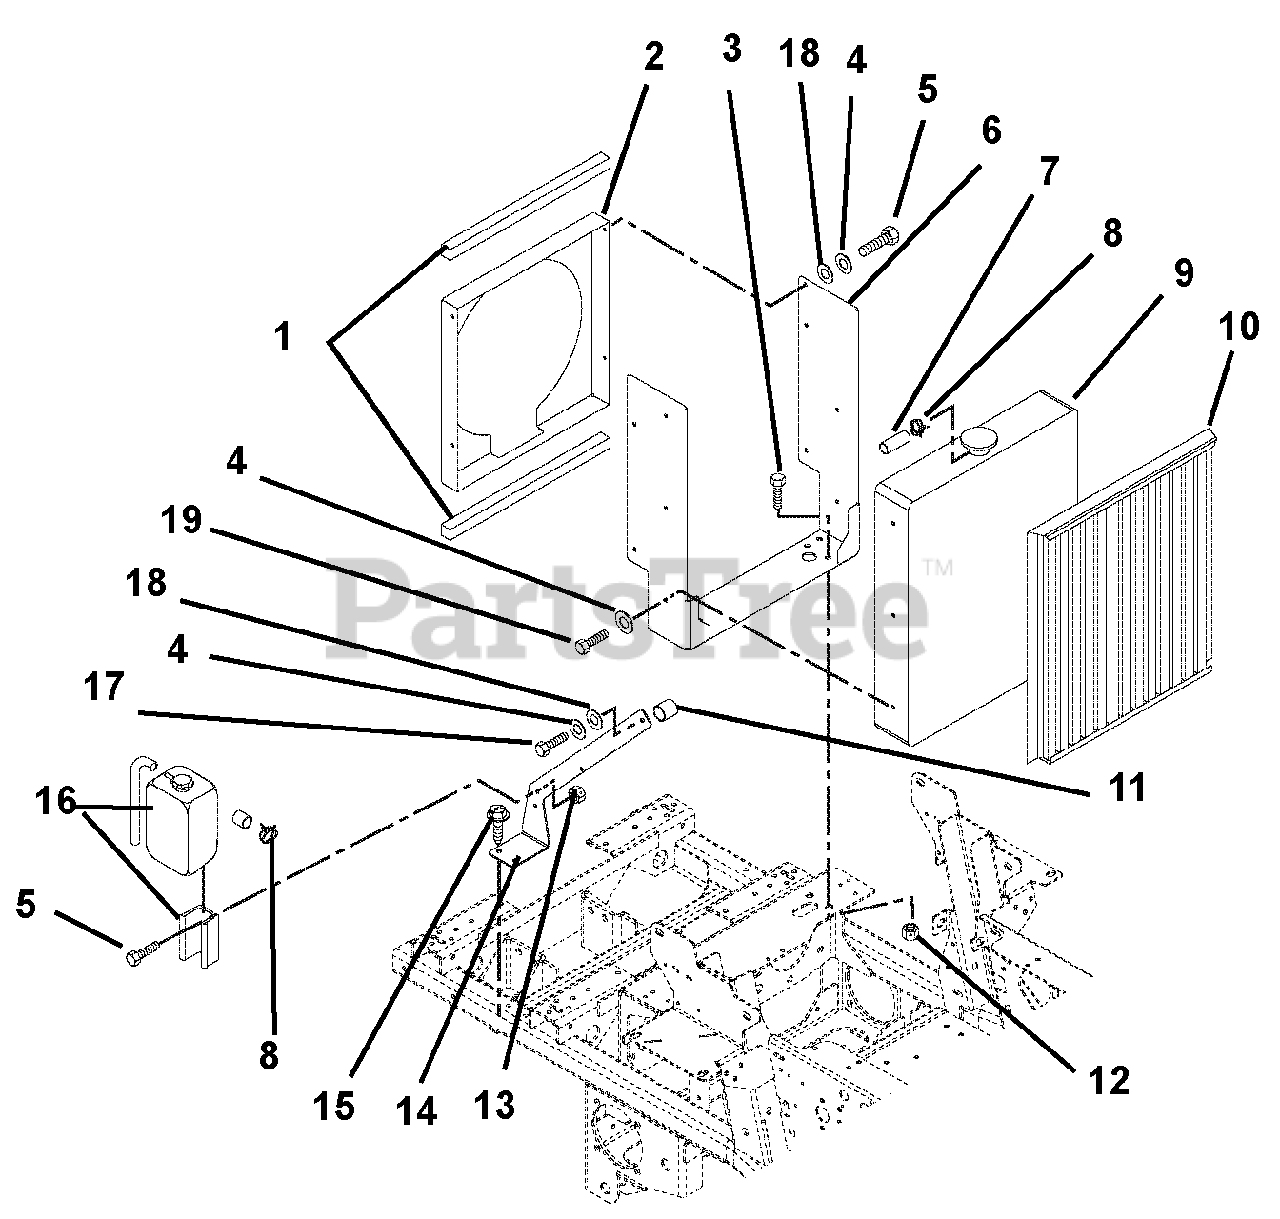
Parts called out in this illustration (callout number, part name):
1	Seal, Trim-LOK Bulk .06 Bubble
2	Weldment, Radiator Shroud
3	Bolt, Hex .38-16 x 1.00 Grade 5
4	Washer, Locking .25 x .062 Regular
5	Bolt, Hex .25-20 x .75 Grade 5
6	Bracket, Radiator Mounting
7	Gas Line, Bulk .25 ID
8	Clamp, Hose Wire .49/.51 x .116
9	Radiator (Comes with the engine)
10	Screen, Radiator
11	Spacer .328 x .76 x 1.01
12	Nut, Locking Top Flange .38-16
13	Nut, Locking Top Flange .25-20
14	Bracket, Overflow Mounting
15	Screw, Tapping .38-16 x .75 Hex Washer Head
16	Reservior Overflow (Comes with the engine)
17	Bolt, Hex M6-1.00 x 45
18	Washer, Flat Steel .281 x .62 x .065
19	Bolt, Hex M6-1 x 16
